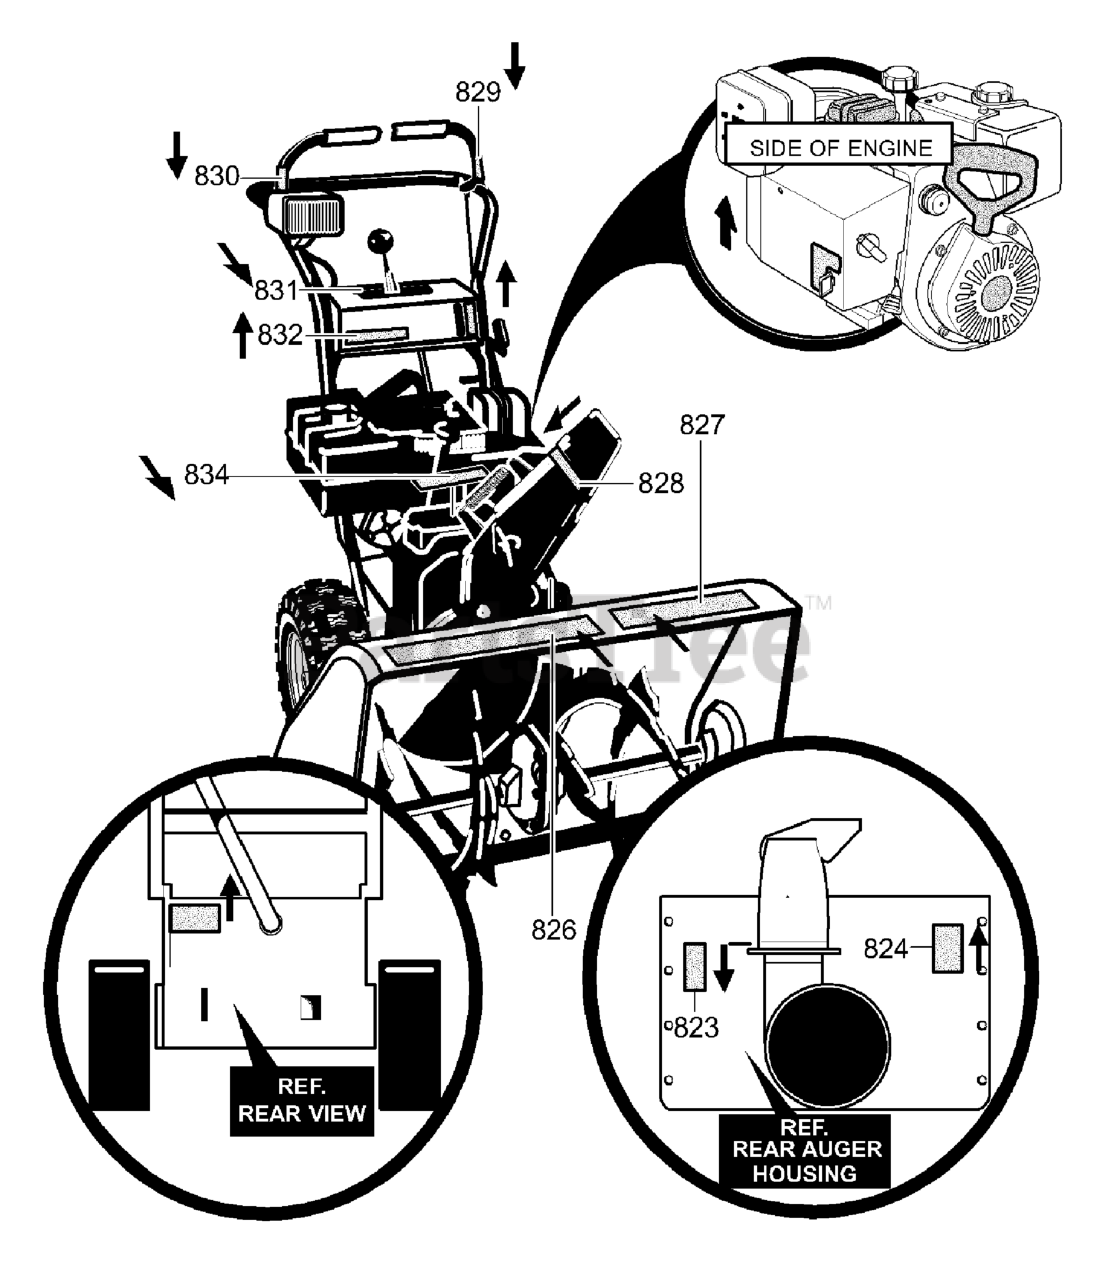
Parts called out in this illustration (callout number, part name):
823	DECAL, DANGER CHUTE HAND
824	DECAL, DANGER FOOT
826	DECAL, CRAFTSMAN GOLD
827	DECAL, 10.5/29
828	DECAL, STRIPE
829	DECAL, DRIVE CLUTCH
830	DECAL, AUGER CLUTCH
831	DECAL, GEAR SELECTOR
832	DECAL, CRAFTSMAN
834	DECAL, TOOLBOX INFORMATION
